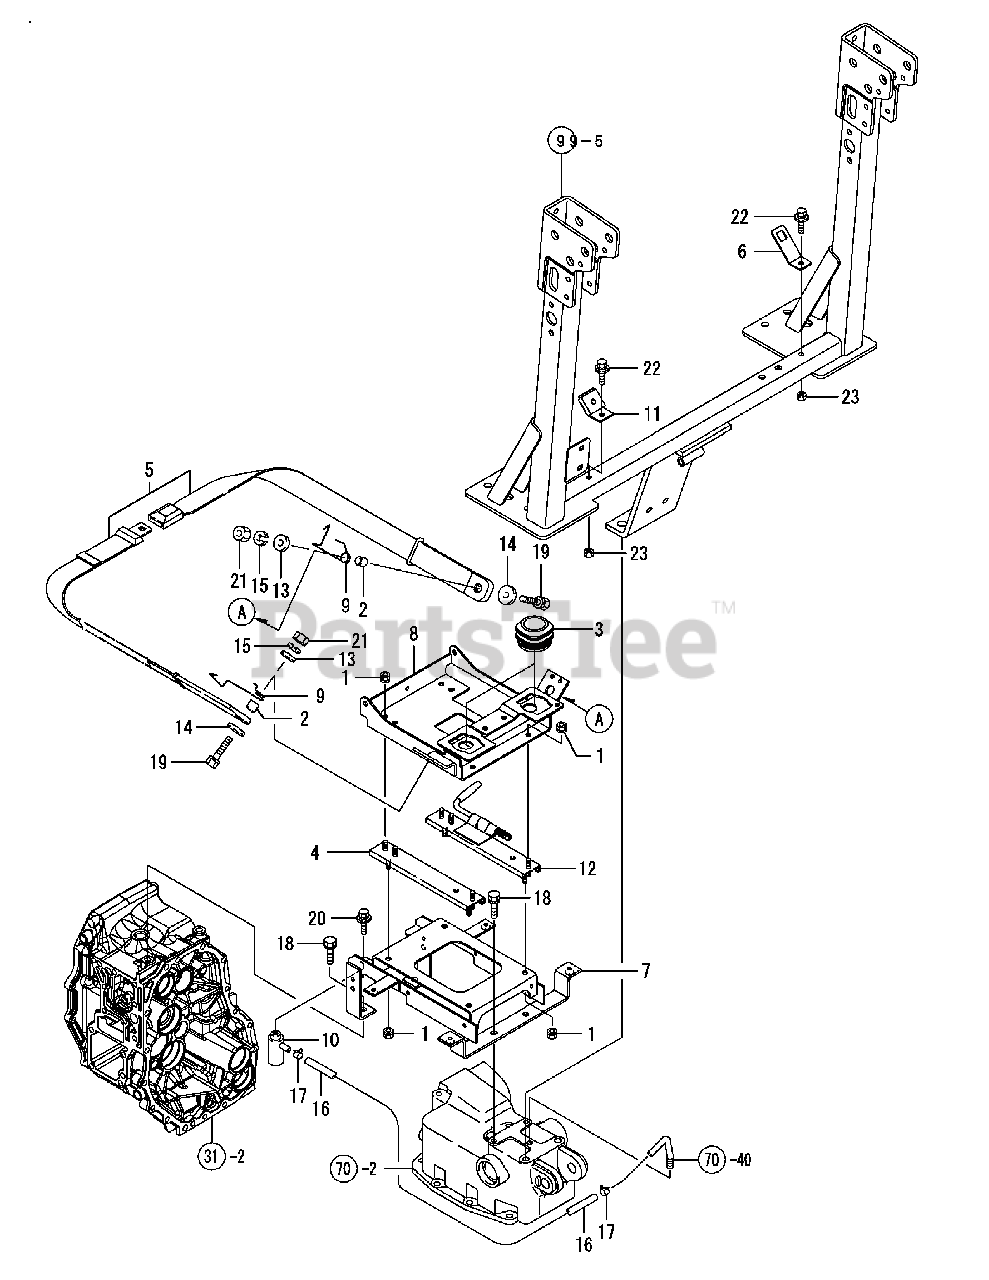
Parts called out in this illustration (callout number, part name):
1	Nut W/Washer 8
2	Collar 10X16X15
3	Rubber, Cushion
4	Adjuster, Belt
7	Bracket Cmp, Seat
12	Adjuster, Seat R
13	Washer 10,Polished
15	Spring Washer 10
18	Bolt W/Washer M10X20
22	Bolt M 8X 16 Plated
